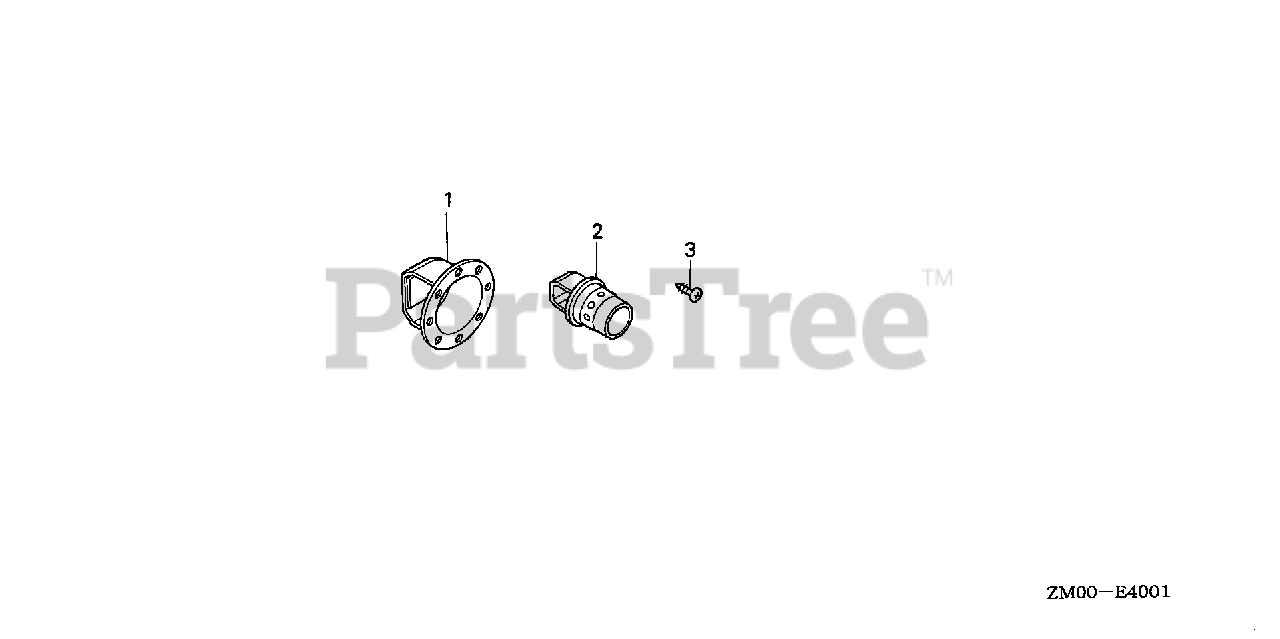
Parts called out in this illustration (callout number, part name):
1	CAP, MUFFLER
2	DEFLECTOR, MUFFLER
3	SCREW, TAPPING (4X6)
